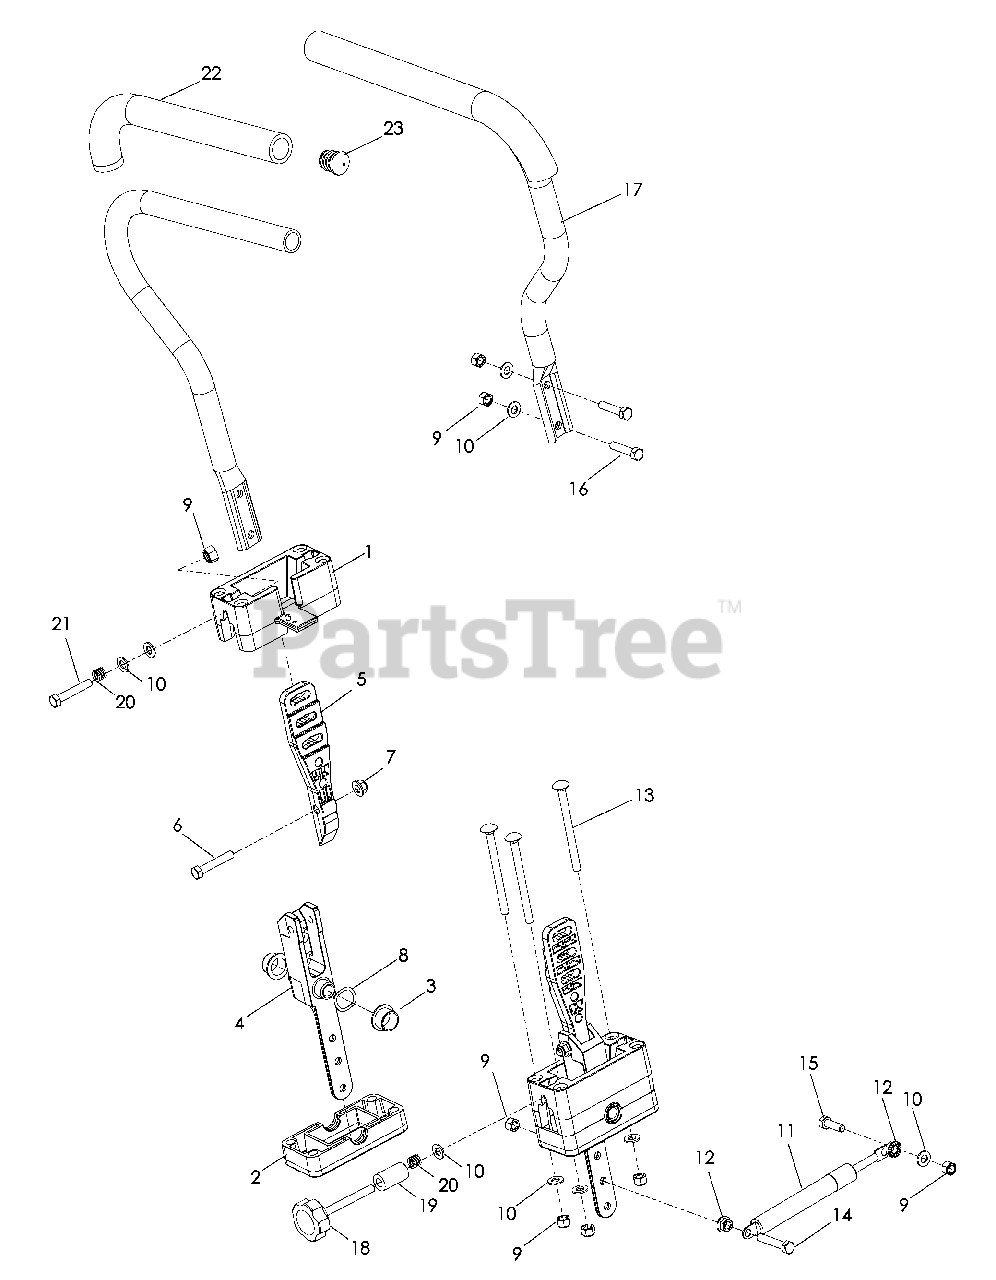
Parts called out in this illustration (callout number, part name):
1	BLOCK, UPPER
2	BLOCK, LOWER
3	BEARING, FLANGE
4	PIVOT SECTION, DRIVE
5	MOUNT, DRIVE CONTROL
6	HCS 5/16-18 x 1¾
7	NUT 5/16-18 FLANGE NYLOC
8	WASHER, .825 x 1.087 WAVE
9	NUT 5/16-18 HEX NYLOC
10	WASHER 5/16 SAE FLAT
12	NUT 5/16-18 HEX WHIZLK
13	RHSNB 5/16-18 x 4
14	HCS 5/16-18 x 1¾ TPBLT
15	HCS 5/16-18 x 1
16	HCS 5/16-18 x 1½
17	LEVER, w/GRIP
21	HCS 5/16-18 x 2 TPBLT
22	GRIP, FOAM
